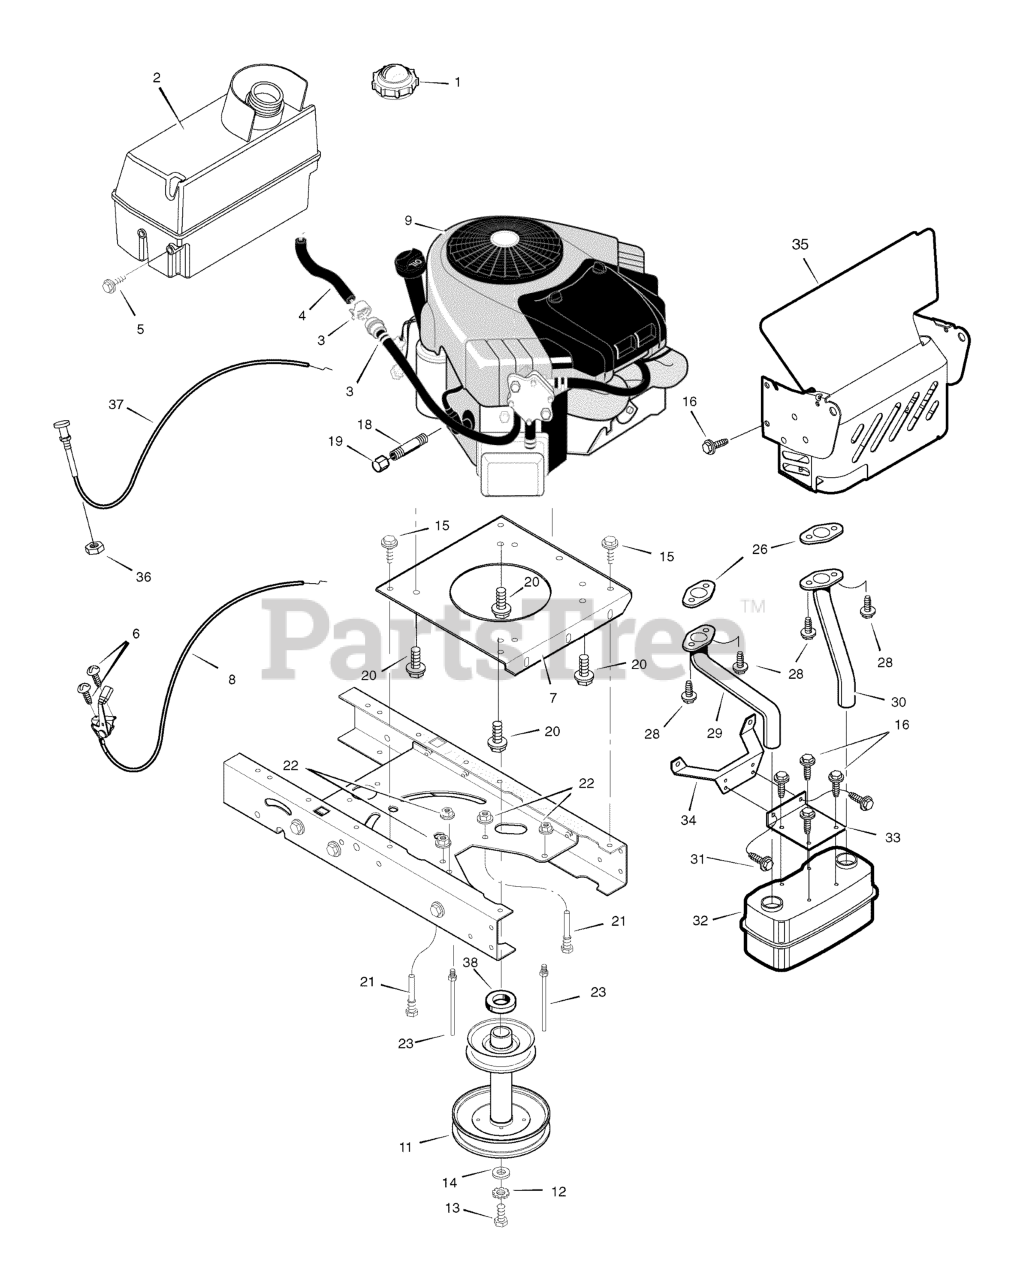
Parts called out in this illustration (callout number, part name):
1	Fuel Cap
2	Fuel Tank
3	Hose Clamp
4	Fuel Line (Must cut to length)
7	Plate, Engine
8	Throttle Control
9	Engine, Briggs & Stratton *
11	STACK PULLEY ASSEMBLY
12	Lockwasher
13	Bolt, Hex
18	Pipe, Oil Drain
19	Cap, Oil Drain
20	Bolt, Engine Mount
21	Guide, Belt
22	Nut, Flange
23	Guide, Belt
26	Gasket, Muffler
28	Screw, Adapter
29	Tube, Right Exhaust
30	Tube, Left Exhaust
32	Muffler
33	Bracket, Muffler
34	Bracket, Muffler Mount
35	Shield, Heat
36	Nut
